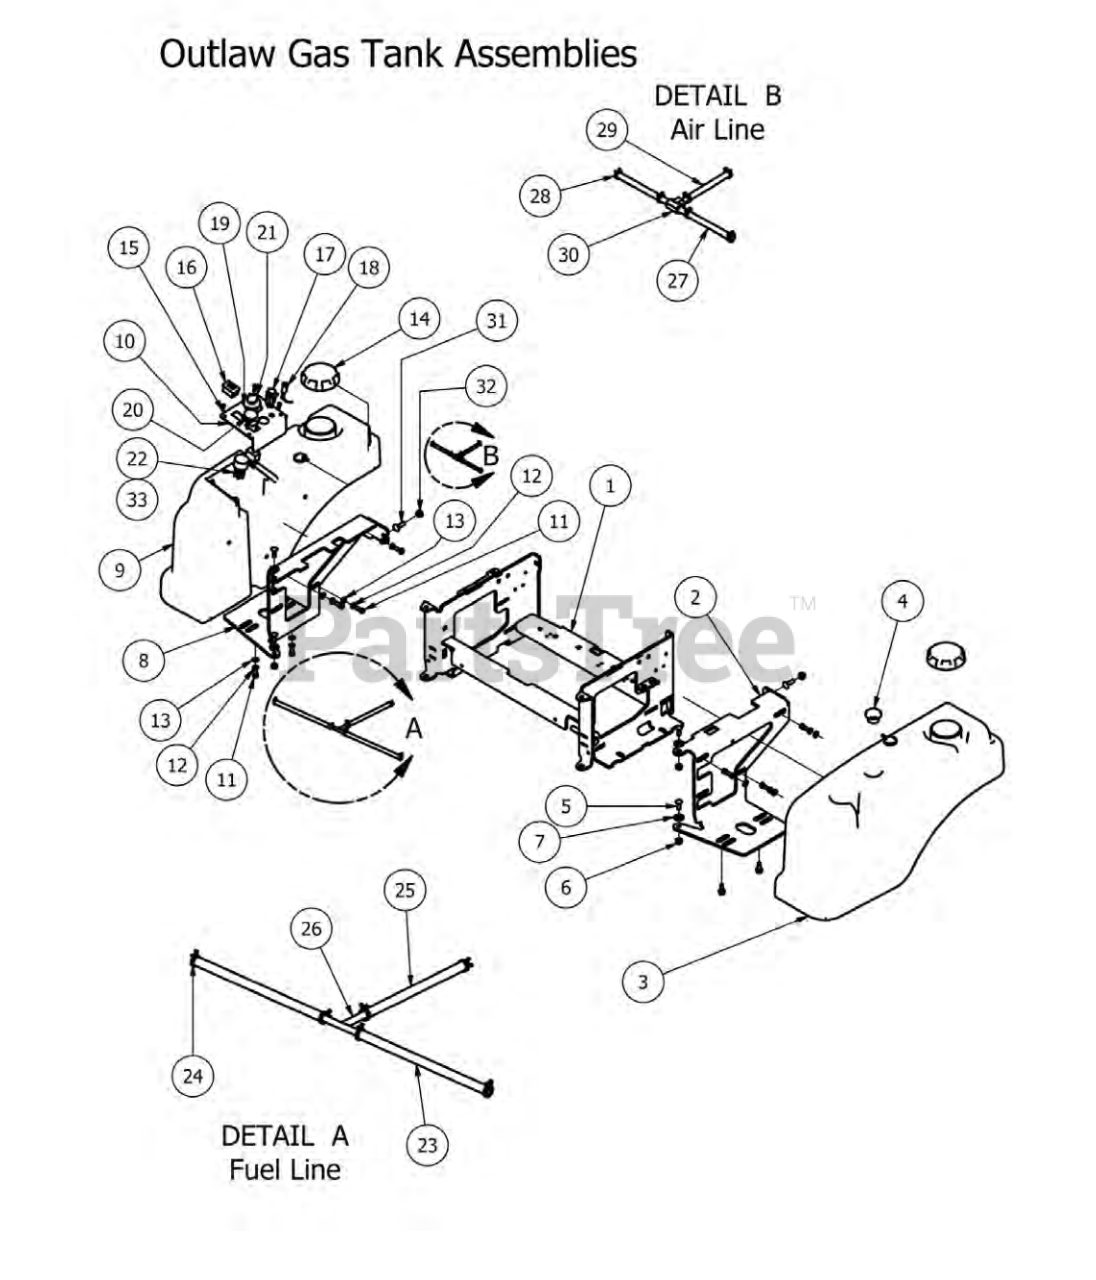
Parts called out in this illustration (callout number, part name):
1	Outlaw Seat Bracket 2012
2	Tank Support 2012 Outlaw (Left)
4	Fuel Gauge and Grommet
5	5/16" x 1" Carriage Bolt
6	5/16-18 Nylon Flange Nut
7	360 ID Plastic Washer
8	Outlaw Tank Support 2012 (Right)
9	Right Tank
10	Outlaw Instrument Panel 2010
11	5/16" x 1" Bolt
12	5/16" Lock Washer
13	5/16" Flat Washer
14	3.5" Tethered Fuel Cap
15	10-32 x 3/8" Button Socket Head Bolt
16	Tachometer
17	12V AUX Connection
19	Ignition Switch
20	PTO Engager
21	Ignition Key
22	Wiring Harness-23hp Briggs/30hp Briggs Outlaw
23	Fuel Line Assembly
24	1/4 fuel clamp
25	1/4" fuel line hose
26	fuel line T
27	1/4" Vinyl Tubing-Black
28	3/16 vinyl clamp
29	3/16 vinyl tubing
30	Brass fuel line T
31	3/8" x 1 1/4" Carriage Bolt
32	3/8" Nylock Flange Nut
33	Wiring Harness- 30hp Kohler 2006 and up
